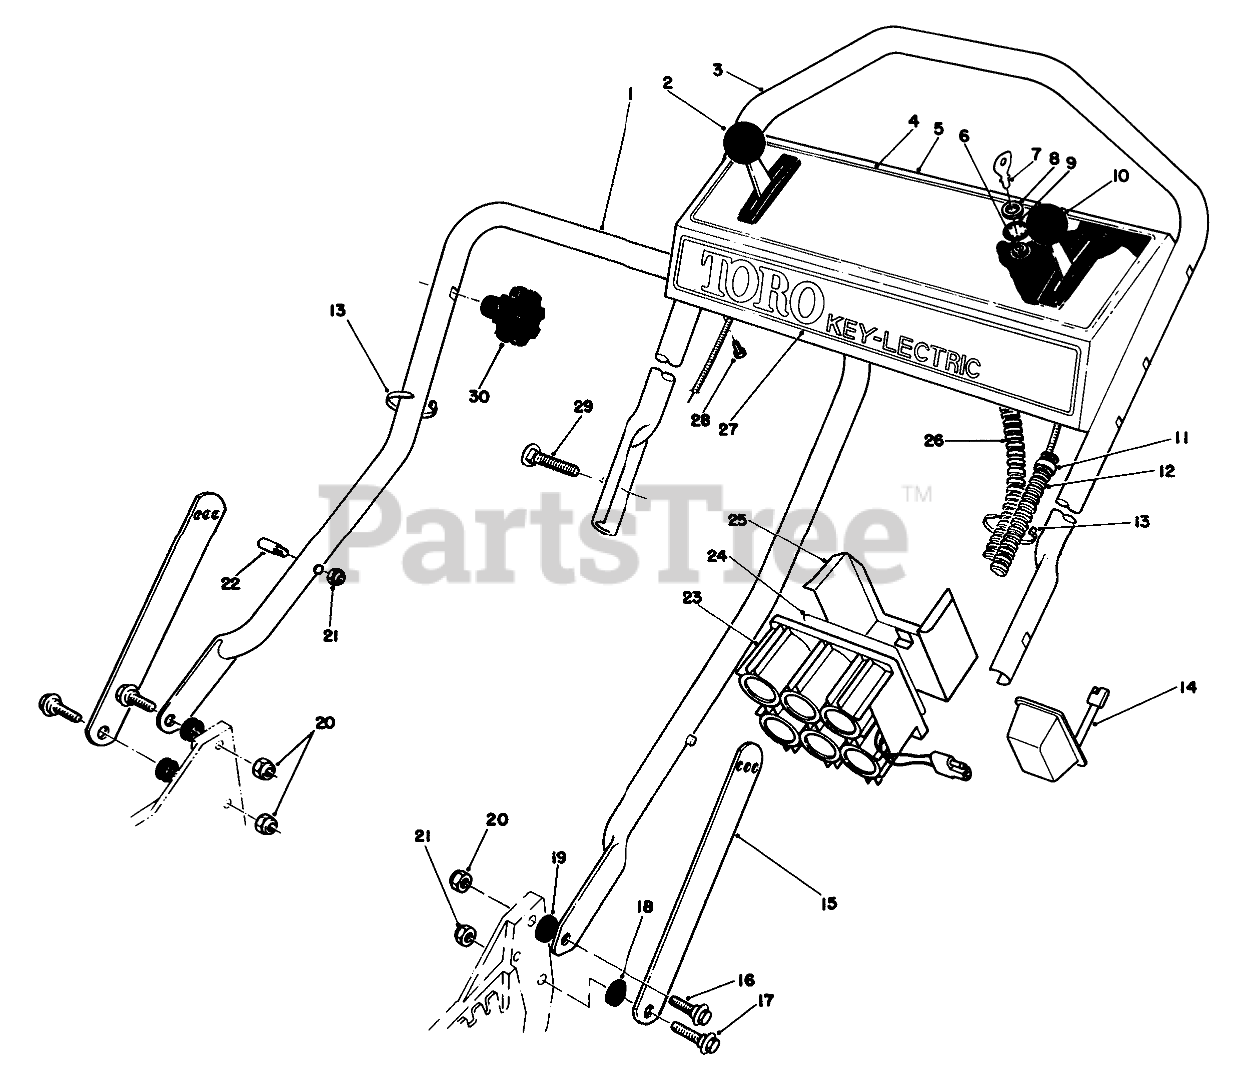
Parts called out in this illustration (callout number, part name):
1	LOWER HANDLE ASM
2	GROUND SPEED CONTROL
3	Handle-Upper
4	INST PANEL DECAL(INTL)
5	Panel-Control (Incl. Ref. #4)
6	Switch-Starter (Incl. Ref. #8-9)
7	Key
8	NUT-HH
9	WASHER-TOOTH, INTERNAL
10	Throttle Control (Sheath Lg. 55-7/8 inch, 142 cm) Wire Lg. 2-5/8 inch, 6.6 cm)
11	FITTING-RING
12	CONTROL CABLE COVER
13	TIE-CABLE
14	Charger
15	Handle Latch
16	SCREW-SHOULDER
17	SCREW-SHOULDER
18	SPACER
19	SPACER
20	NUT-LOCK, NI
21	NUT-LOCK, NI
22	HANDLE PIN
23	BATTERY ASSEMBLY
24	Decal
25	Retainer-Battery
26	WIRE HARNESS
27	Decal-Toro
28	SCREW-HWHTF
29	5/16-18 X 2 HNDLE SCREW
